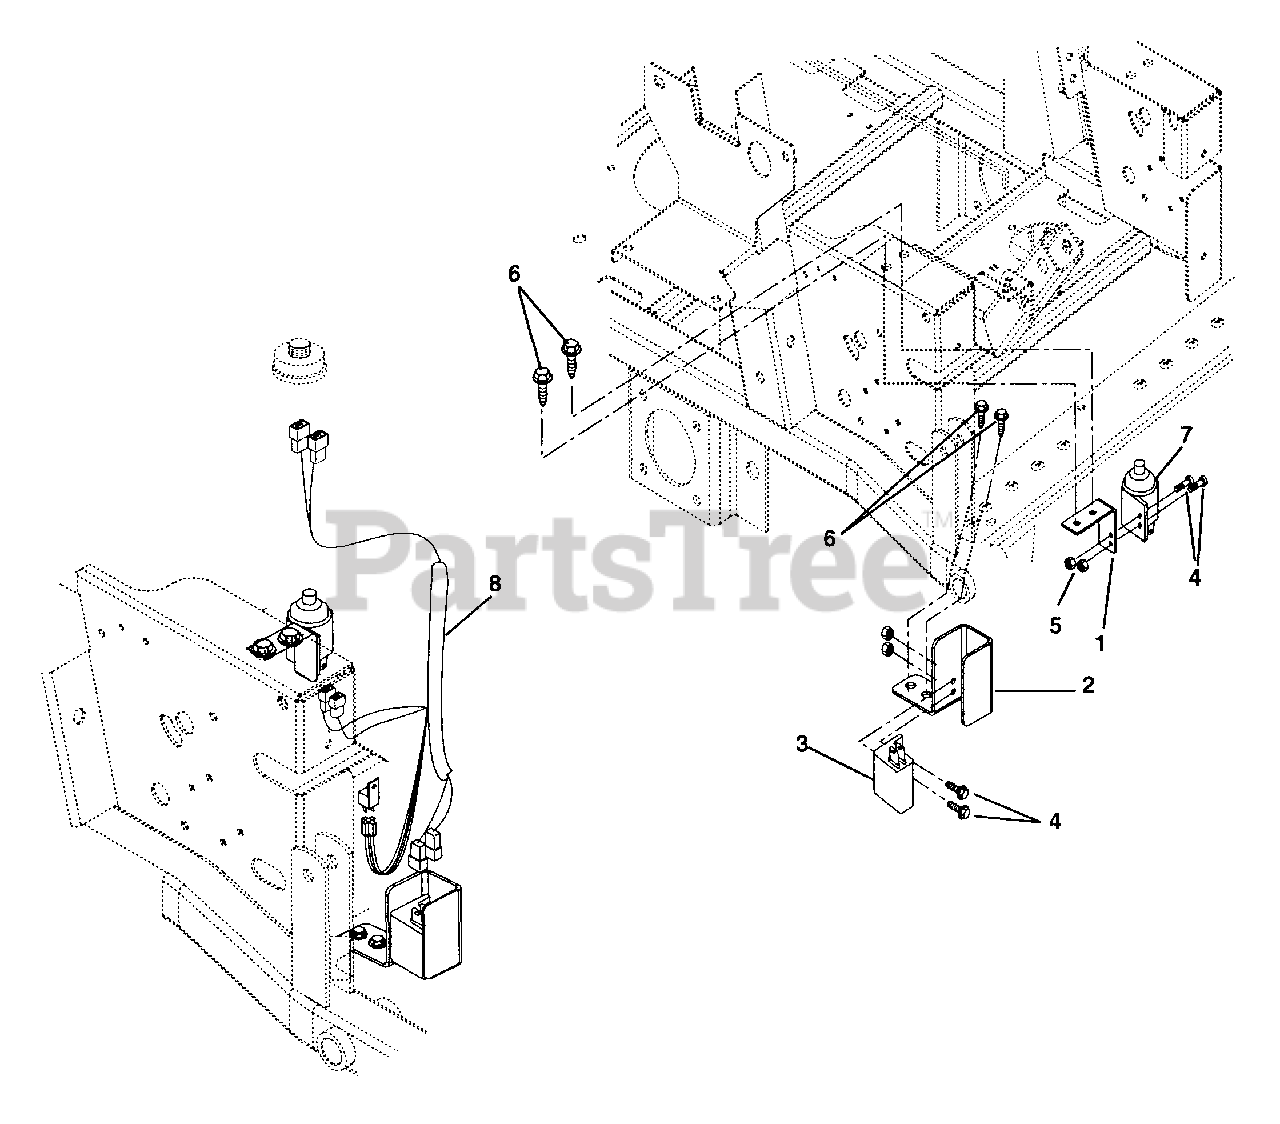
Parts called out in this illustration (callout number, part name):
1	Mount-Switch
2	Bracket-Switch
3	Switch-Single Pole N.O.
4	Screw-Machine 10-24 x .75 Hex Washer Head
5	Nut-Lock-Nylon 10-24 With Insert
6	Screw-Tap .31 x 18 x .50 Hex Washer Head
7	Switch-Single Pole N.O. with Cover
8	Wire Harness-CE Adaptor
